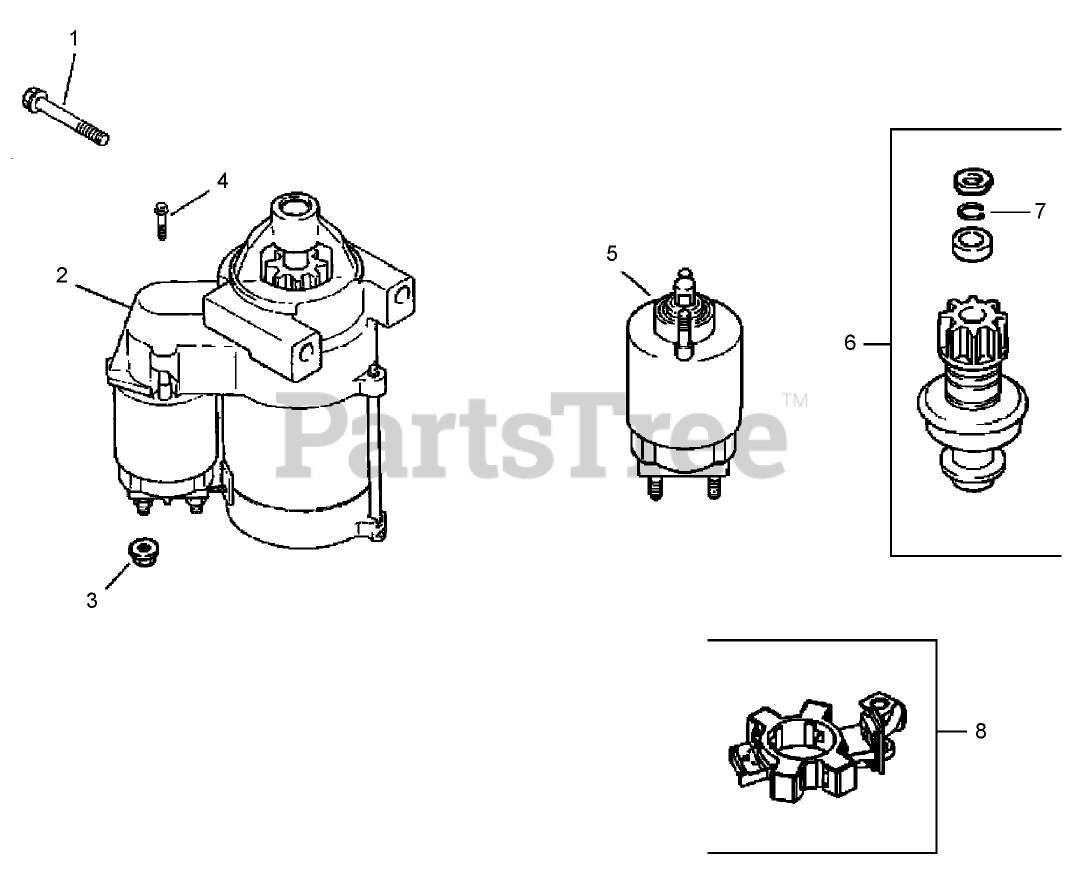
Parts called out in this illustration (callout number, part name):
1	SCREW-FLG (M8X1.25X80)
2	Starter, solenoid shift (Incl. 3-8)
3	NUT-FLANGE (M8X1.25)
4	SCREW-TORX HEAD, EXTERNAL
5	Kit, solenoid (Incl. 4)
6	Kit, drive (Incl. 7)
7	RING-RETAINING
8	BRUSH HOLDER KIT
